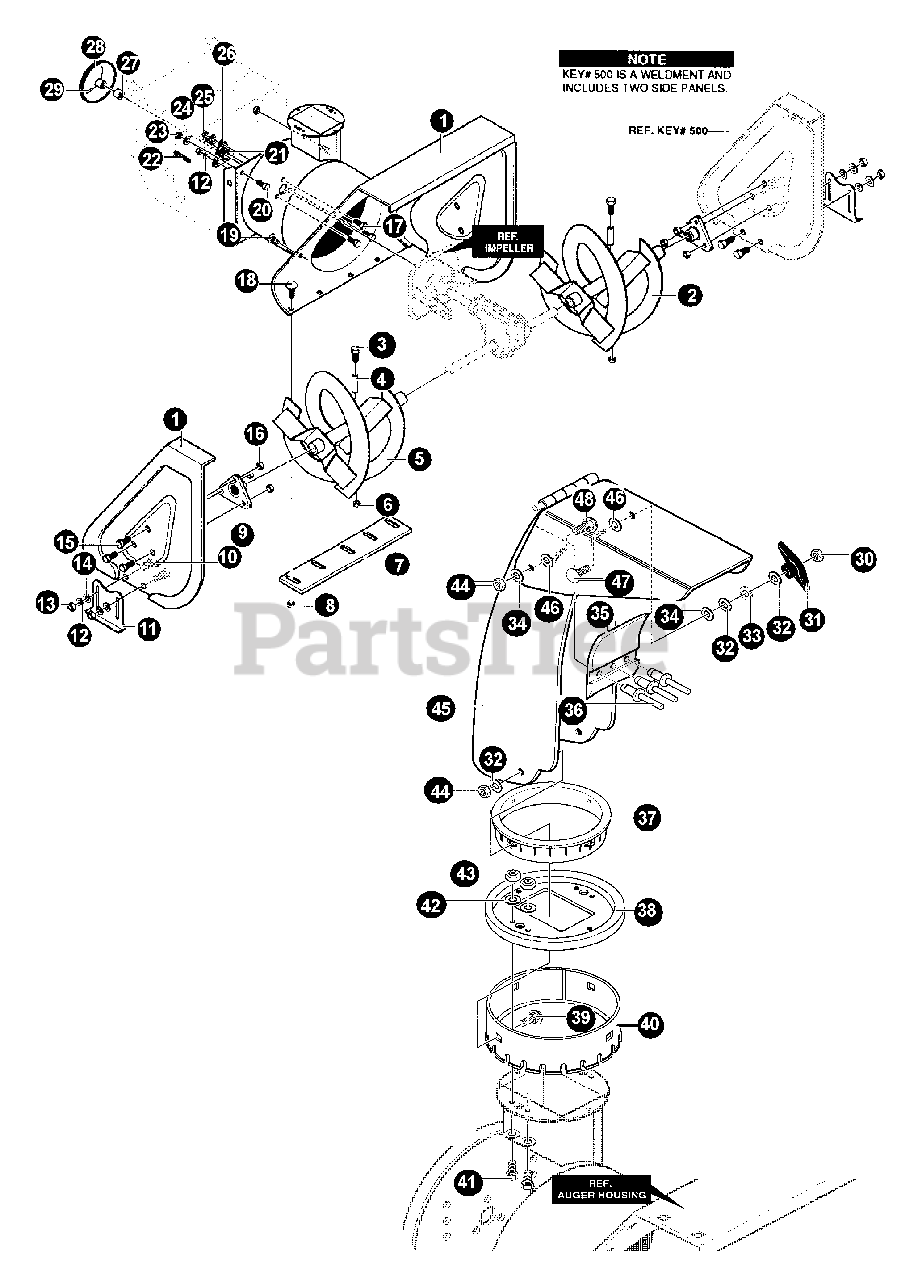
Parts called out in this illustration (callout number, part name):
1	AUGER INTAKE ASSY
2	AUGER ASSY - RIGHT
3	SCREW 1/4"-20
4	SPACER
5	AUGER ASSY - LEFT
6	NUT, 1/4"-20
7	BLADE, SCRAPER
8	NUT, 1/4"-20
9	BEARING, FLANGE 0.754 ID
10	BOLT, CARRIAGE 5/16-18×0.75
11	SKID, HEIGHT
12	WASHER
14	WASHER
15	SCREW, 5/16-18×0.75 WDFLWAHLK
16	NUT, 5/16-18 WDLF WHIZ
17	SCREW 5/16"-18×0.75
18	BOT, 1/4-20×0.75 CARR
19	FASTENER, RATCHET
20	SCREW - 3/8-16×0.75" -- HEX HEAD CAP
21	BEARING, BALL
22	KEY, SQUARE 0.18SQX88LG
23	NUT, 3/8"-16
24	WASHER. REGSPTLK 0.393×0.68×0.10
25	NUT, 5/16"-18
26	RETAINER, BEARING
27	SPACER
28	PULLEY
29	SCREW - 5/16-28×0.63" -- HEX HEAD CAP
31	KNOB, T 2 BLADE W/5/16-18 NUT
32	WASHER
33	WASHER
34	WASHER, PLASTIC
35	FLAP, CHUTE INSERT
36	RIVIT
37	RETAINER, RING INNER
38	COLLAR, CH
39	BOLT, 5/16-18×1.00 CARRLN
40	RETAINER, RING OUTER
41	SCREW 1/4 - 20×75 HHC
42	WASHER
43	NUT, 1/4"-20
44	NUT, 5/16 - 18
45	CHUTE ASSY
46	WASHER, PLASTIC
47	BOLT - 5/16-18×1" -- CARRIAGE
48	BOLT, CARRIAGE 5/16-18×0.75
